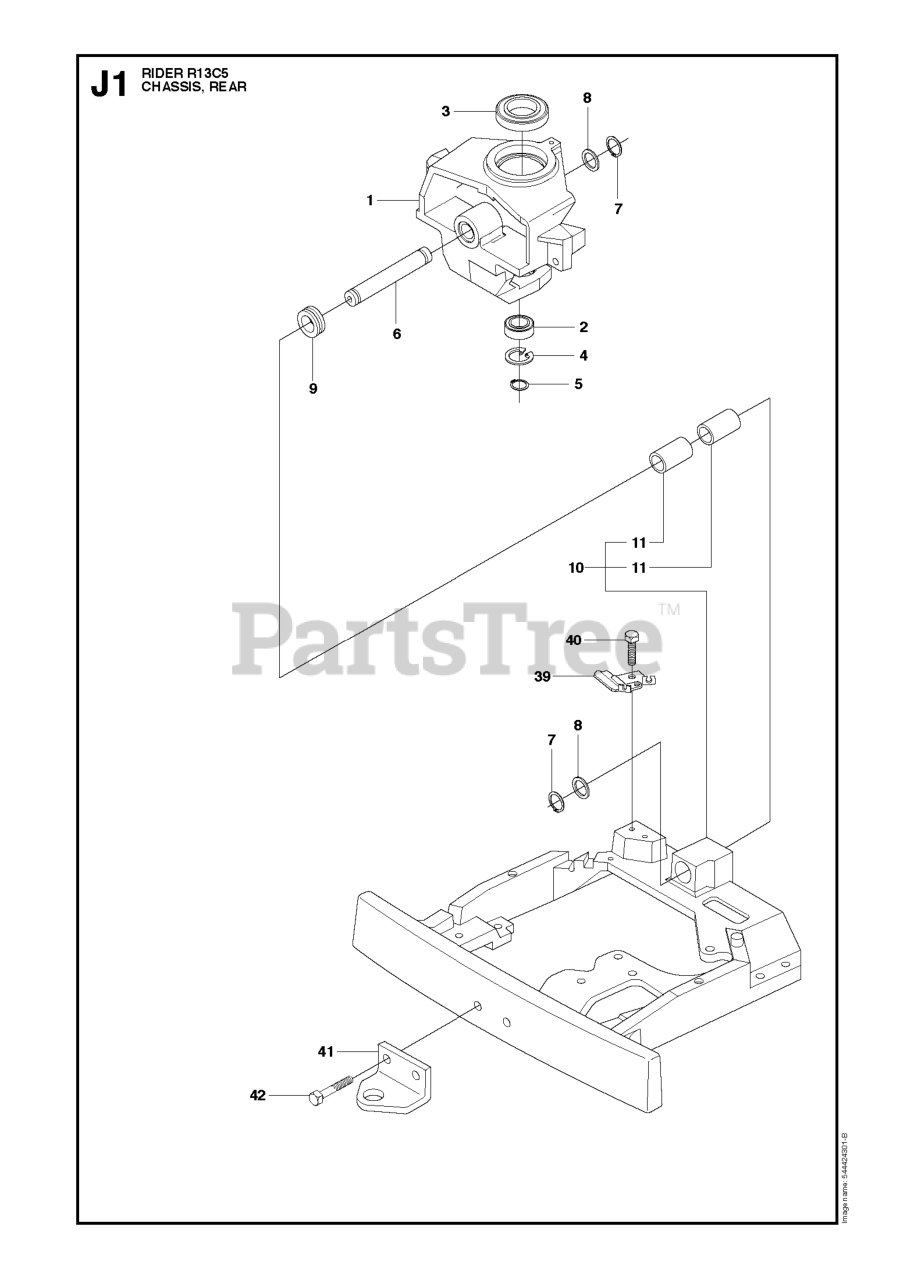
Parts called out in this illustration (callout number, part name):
2	Ball Bearing 6005-2rs
3	BALL BEARING 6010 2RS1
4	CIRCLIP SGH 47
5	RETAINING RING SGA 25
7	RETAINING RING SGA 25
42	Screw M10x25
